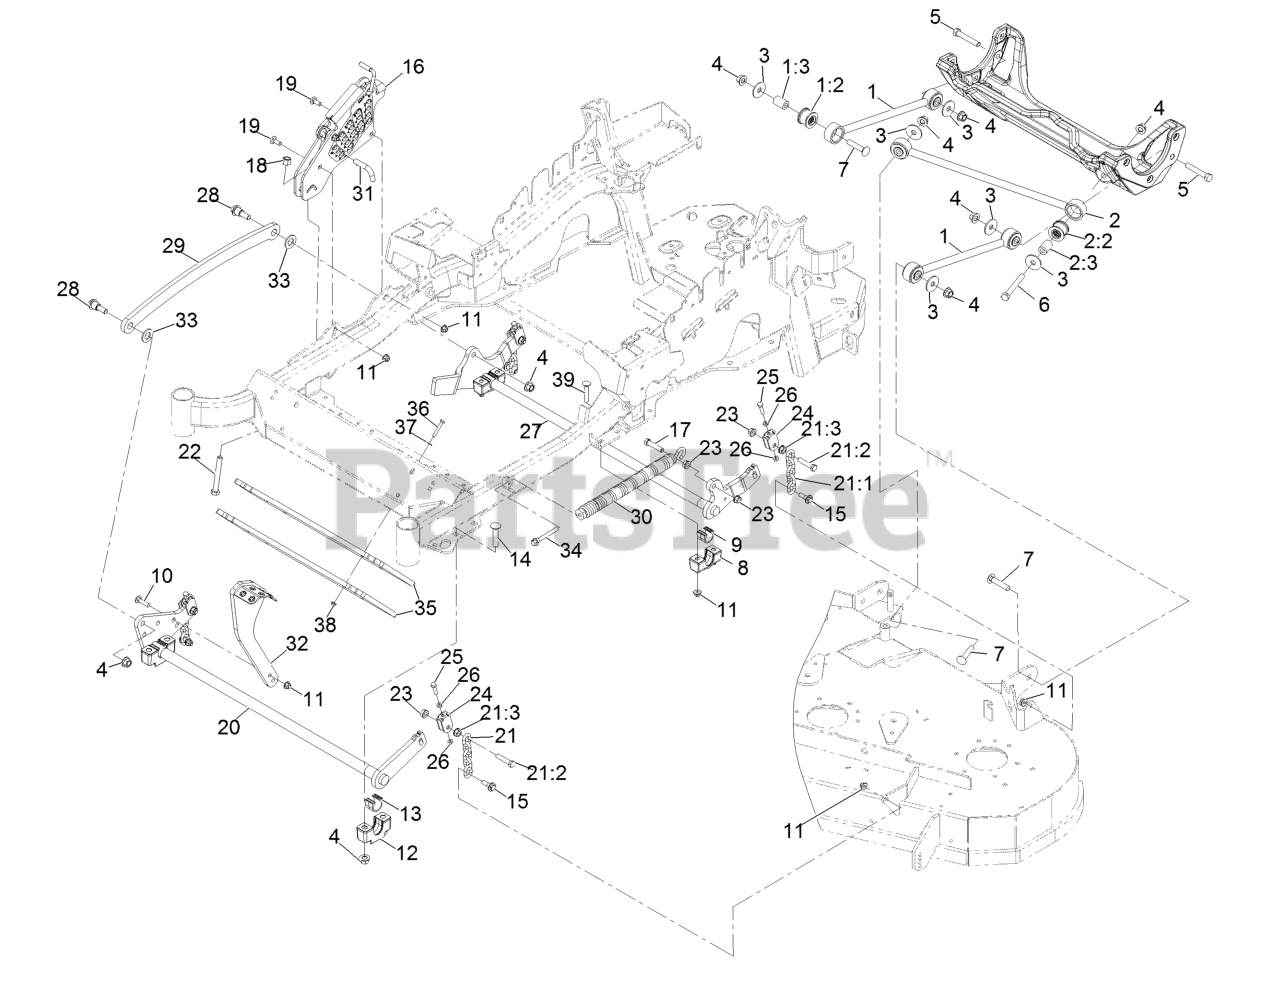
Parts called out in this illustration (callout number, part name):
1	Deck Strut ASM
1:2	Bushing-Suspension,Rubber
2	Panhard Rod ASM
2:2	Bushing-Suspension,Rubber
4	Nut-Lock 1/2-13
5	Screw-HH 1/2-13 X 3
6	Screw-HH 1/2-13 X 4
7	Bolt-Carriage 1/2-13 X 2 1/2
8	Support-Cross Shaft,Bearing Rear
9	Bearing-Cross Shaft, Rear
10	Bolt-Carriage 3/8-16 X 1 1/2
11	Nut-Nyloc 3/8-16 Flg
12	Support-Cross Shaft,Bearing
13	Bearing-Cross Shaft, Front
14	Bolt-Carriage 1/2-13 X 2 1/2 Spl Neck
15	Screw-Hex Flange 3/8-16 X .80
16	HOC ASM
17	Screw-HH 7/16-14 X 2
18	Nut-Nyloc 1/2-13
19	Bolt-Carriage 3/8-16 X 1
20	Decklift-Front
21	Deck Lift Chain ASM
21:1	Chain-Lift, Deck
21:2	Screw-HH 7/16-14 X 2
21:3	Nut-Whizlock 7/16-14
22	Bolt-HH 1/2-13 X 4 Tap
23	Nut-Whizlock 7/16-14
24	Yoke-Adjust, Deck
25	Screw-HH 5/16-18 X 1 1/4
26	Nut-Jam 5/16-18
27	Lift-Deck, Rear
28	Screw-Shoulder HHF 1/2-13 X 1.12
29	Link-Lift, Deck
30	Spring-Extension
31	Pin-HOC
32	Lever-Foot
33	Washer-3/4 SAE
34	Screw-Shcs 3/8-16 X 2.212
35	Weight-Toe Board
36	Screw-HH 1/4-20 X 1 3/4
37	Washer-1/4 SAE
38	Nut-Nyloc 1/4-20 Flg
39	Bolt-Carriage 3/8-16 X 2 1/4
